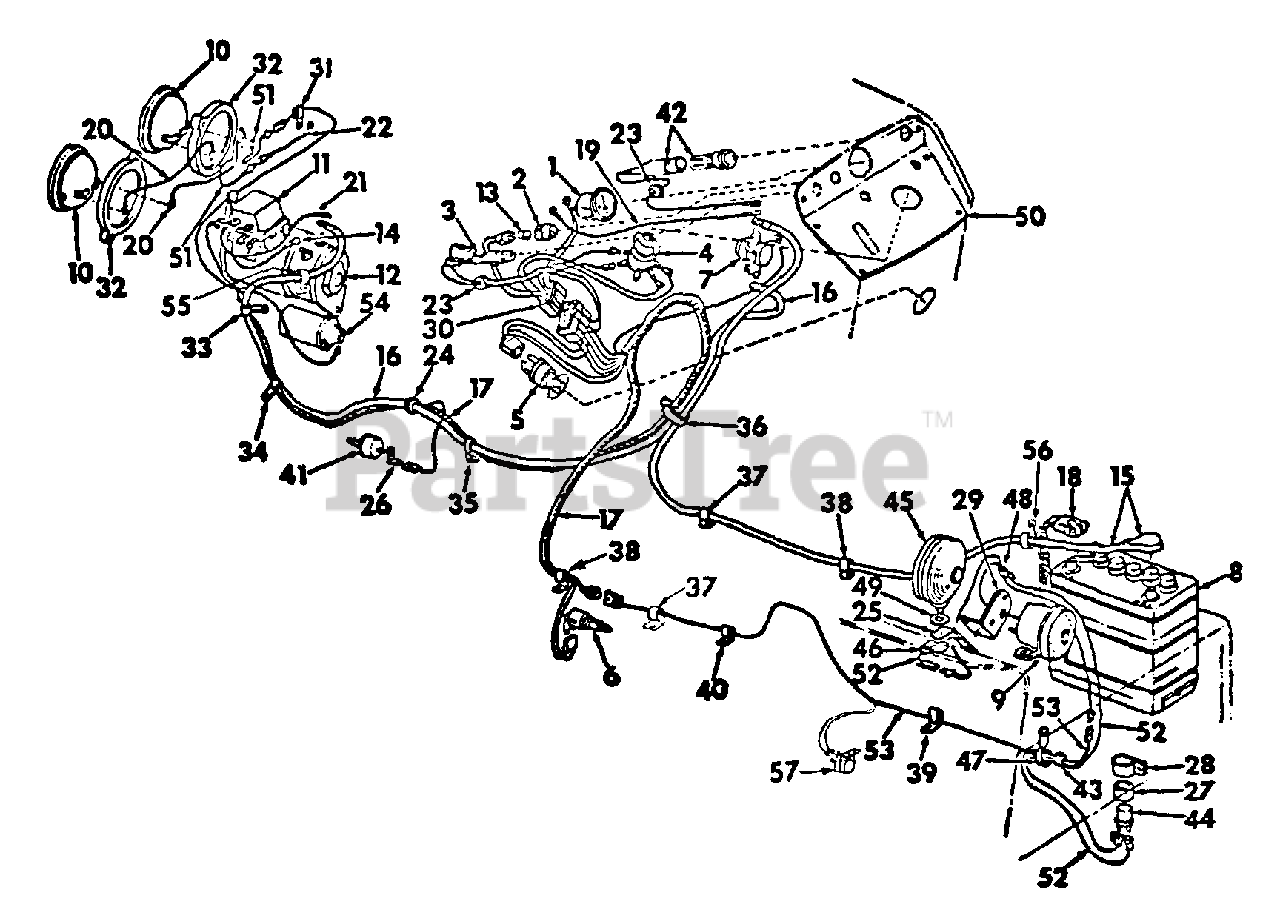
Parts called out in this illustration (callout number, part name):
1	INDICATOR ASSY, CHARGE
2	SOCKET ASSY, OIL TELLITE
3	HOUSING ASSY, FUSE
4	SWITCH ASSY, LIGHTING
5	SWITCH ASSY, BATTERY IGNITION KEY
6	SWITCH, NEUTRAL STARTING
7	SWITCH, MAGNETIC
8	BATTERY, 12 VOLT
9	LIGHT ASSY, TAIL 12 VOLT
10	UNIT ASSY, SEALED BEAM HEAD LIGHT
11	REGULATOR ASSY, VOLTAGE
12	MOTOR GENERATOR ASSY
13	LAMP, NO. 257 12 VOLT
14	LEAD, A TERMINAL TO REGULATOR
15	CABLE ASSY, BATTERY TO MAGNETIC SWITCH
16	CABLE ASSY, MAGNETIC SWITCH TO GENERATOR
17	HARNESS ASSY, CABLE
18	STRAP ASSY, BATTERY TO GROUND
19	CABLE ASSY, CHARGE INDICATOR TO MAGNETIC SWITCH
20	CABLE ASSY, RH LIGHT TO LH LIGHT
21	LEAD, F TERMINAL TO REGULATOR
22	CABLE ASSY, HEAD LIGHT TO CONNECTOR
23	GROMMET, RUBBER
24	GROMMET, RUBBER
25	SUPPORT, WARNING LIGHT
26	TERMINAL, OIL PRESSURE SWITCH ANGLE
26	TERMINAL, OIL PRESSURE SWITCH
27	ABSORBER, FLASHER MOUNTING
28	BRACKET, FLASHER MOUNTING
30	CABLE ASSY, INSTRUMENT PANEL
31	CLIP, CABLE HARNESS RADIATOR & MOTOR GENERATOR
32	RING, HEAD LIGHT CLAMP
32	RING, HEAD LIGHT RUBBER
33	CLIP, CABLE HARNESS MOTOR GENERATOR
34	CLIP, CABLE HARNESS & BATTERY CABLE
35	CLIP, CABLE HARNESS FRAME RH
36	CLIP, CABLE HARNESS -WELDED ON PEDESTAL
37	CLIP, CABLE HARNESS
38	CLIP, BATTERY CABLE RH FRAME AND LH FRAME
39	CLIP, BATTERY CABLE
40	CLIP, TAIL LIGHT
41	SWITCH ASSY, OIL PRESSURE
42	LIGHTER ASSY, CIGARETTE
43	GROMMET, RUBBER
44	FLASHER, WARNING LIGHT
45	LIGHT ASSY, FLASHING WARNING
46	CLIP, WARNING LIGHT CABLE
47	CLIP, TAIL LIGHT CABLE
48	CLIP, TAIL LIGHT CABLE
49	GASKET, WARNING LIGHT
50	PANEL, INSTRUMENT
51	CABLE ASSY, HEAD LIGHT JUNCTION
52	CABLE ASSY, WARNING LIGHT
53	HARNESS ASSY, TAIL LIGHT & IPTO STARTING SWITCH
54	COIL ASSY, IGNITION
55	CLIP, CABLE
56	CLIP, BATTERY CABLE ON FRONT MOUNTING BOLT
57	SWITCH ASSY, SAFETY STARTING
